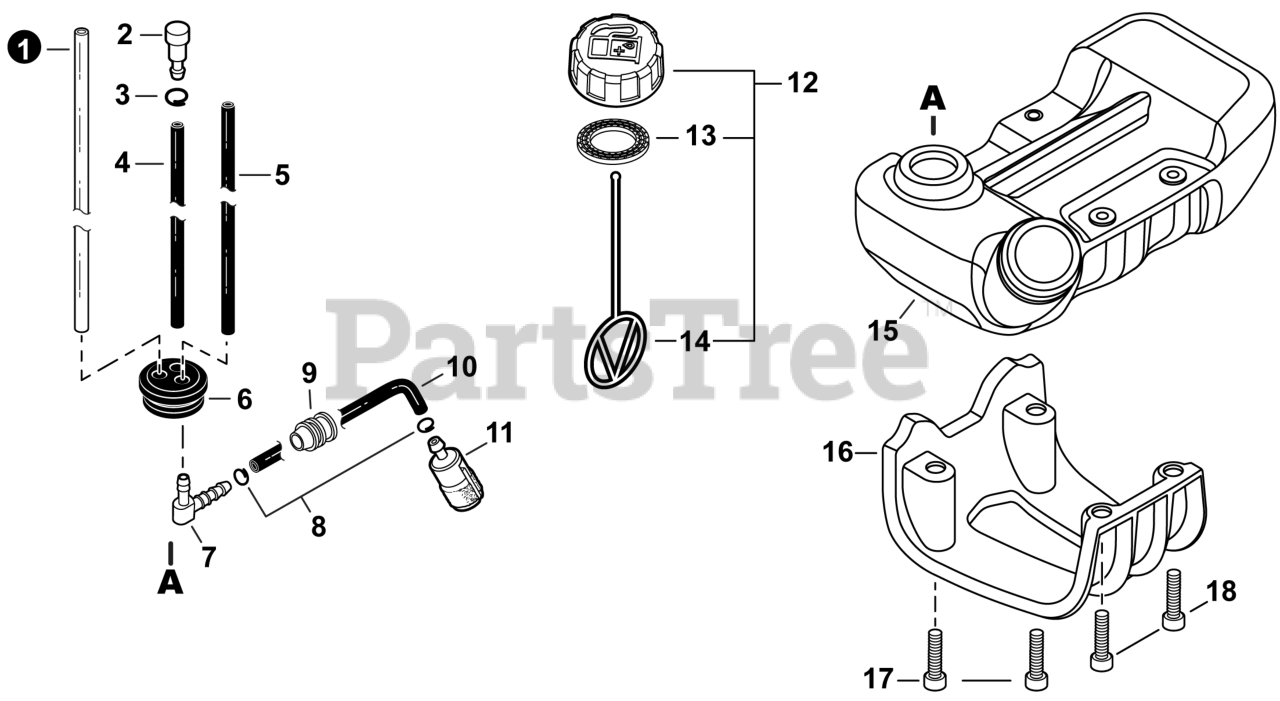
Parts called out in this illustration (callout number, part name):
1	PIPE, FUEL 3x6x85 CLEAR
2	VENT ASSY
3	CLIP 6.5 MM
4	PIPE, FUEL 3x6x95 BLACK
5	PIPE, FUEL 3x5.5x70 BLACK
6	GROMMET, FUEL
7	CONNECTOR, PIPE
10	PIPE, FUEL 3x5x140x35 BLACK
11	FILTER, FUEL
12	CAP ASSY, FUEL
13	GASKET, FUEL CAP
14	CONNECTOR, CAP L= 123
15	TANK, FUEL
16	GUARD, FUEL TANK
17	BOLT, TORX 5x25
18	BOLT, TORX 5x20
